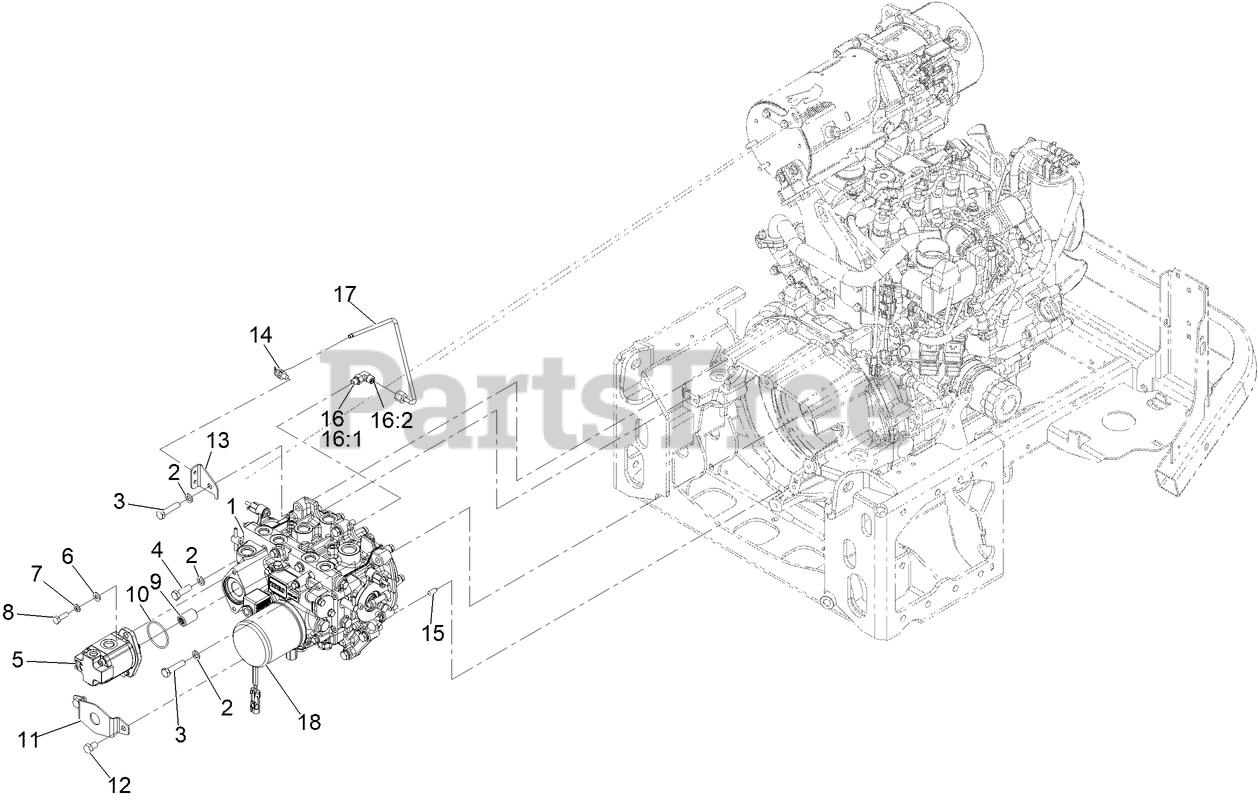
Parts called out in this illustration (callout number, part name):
1	TRANSMISSON ASM
2	WASHER-LOCK
3	SCREW-HH
4	SCREW-HH
5	HYD GEAR PUMP ASM
6	WASHER-PLAIN
7	WASHER-LOCK
8	SCREW-HH
9	COUPLER-SPLINE
11	SHIELD-SEAL
12	SCREW-HH
13	SUPPORT-TUBE
14	CLIP-TIE
15	PIN-DOWEL
16	FITTING-ELBOW, 90 DEG
16:1	O-RING
16:2	O-RING
17	TUBE ASM
18	FILTER-OIL, HYD
